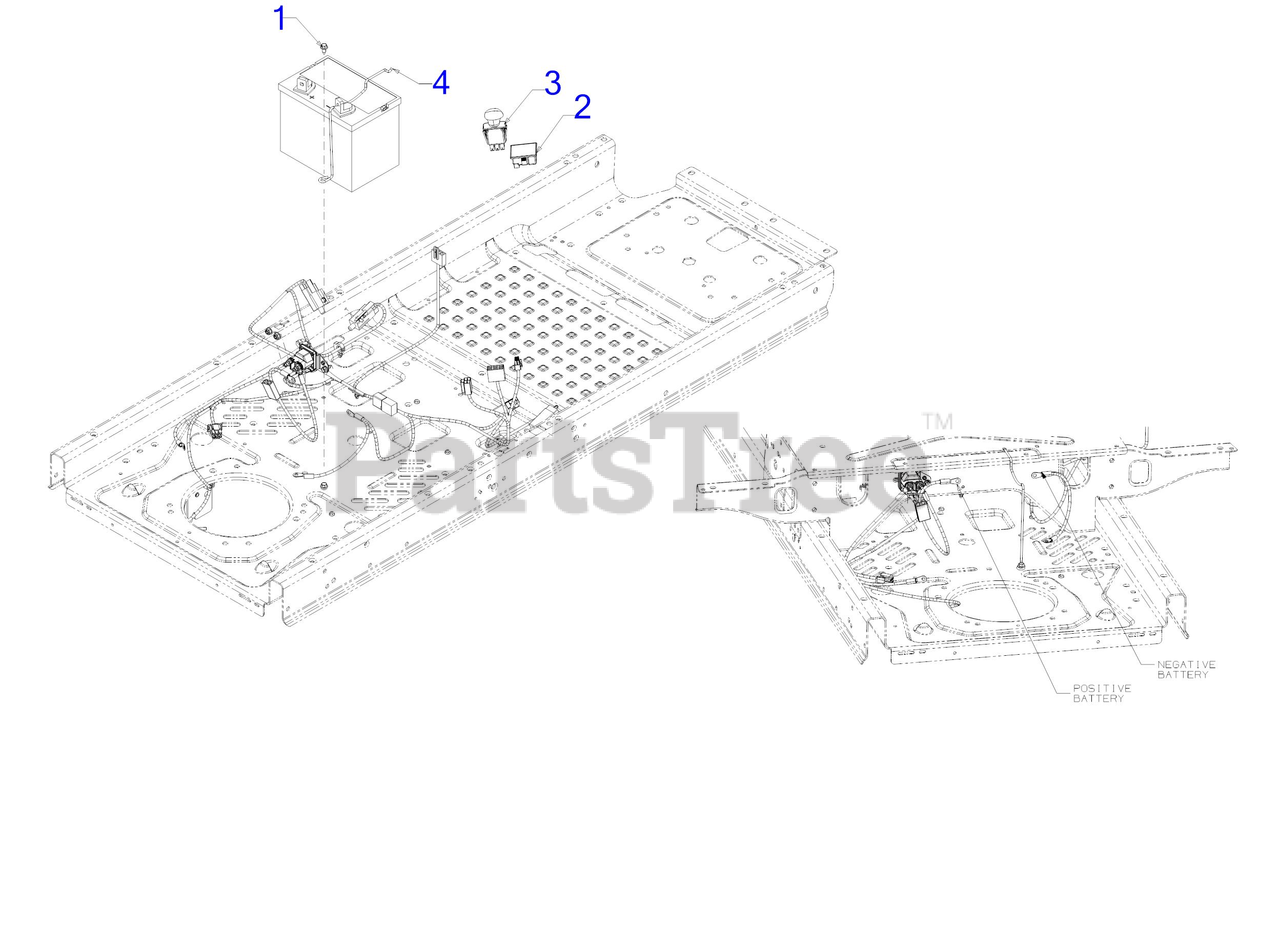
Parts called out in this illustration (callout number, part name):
1	SCREW 1/4-20X.625
2	HOUR/SVC METER
3	PTO SWITCH (YELLOW KNOB)
4	BATTERY RETAINER
